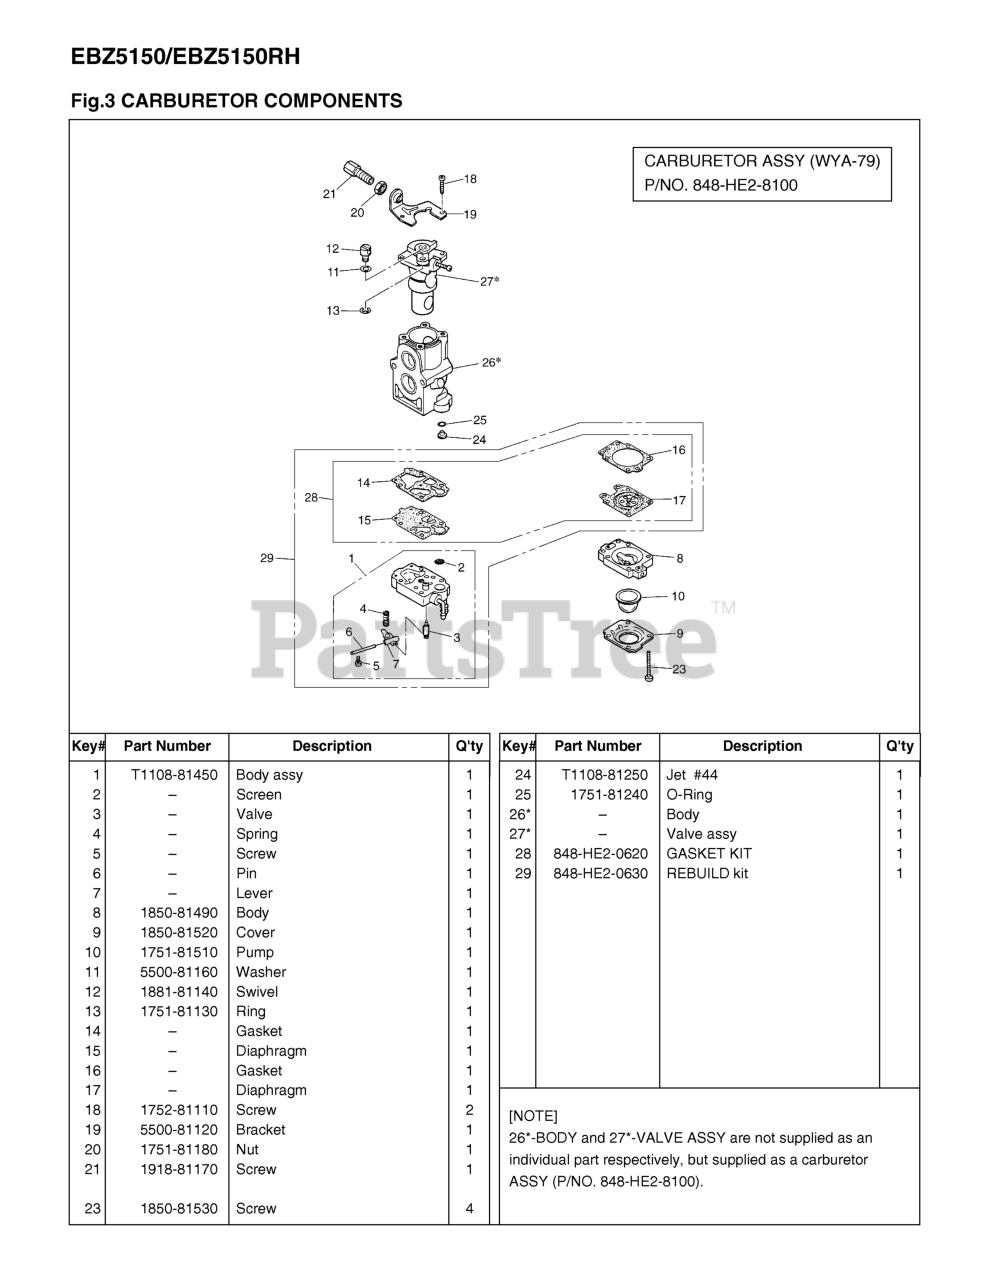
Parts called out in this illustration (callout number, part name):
1	BODY ASSY.
2	SCREEN
3	VALVE
4	SPRING
5	SCREW
6	PIN
7	LEVER
8	BODY, PURGE
9	COVER, PUMP
10	PUMP, PRIMING
11	WASHER
12	SWIVEL
13	RING
14	GASKET
15	DIAPHRAGM
16	GASKET
17	DIAPHRAGM
18	SCREW
20	NUT, CABLE ADJUSTER
21	SCREW, CABLE ADJUSTER
23	SCREW
24	JET (RPLST104481250)
25	RING, O
26	CARBURETOR
27	CARBURETOR
28	GASKET KIT
29	REBUILD KIT
